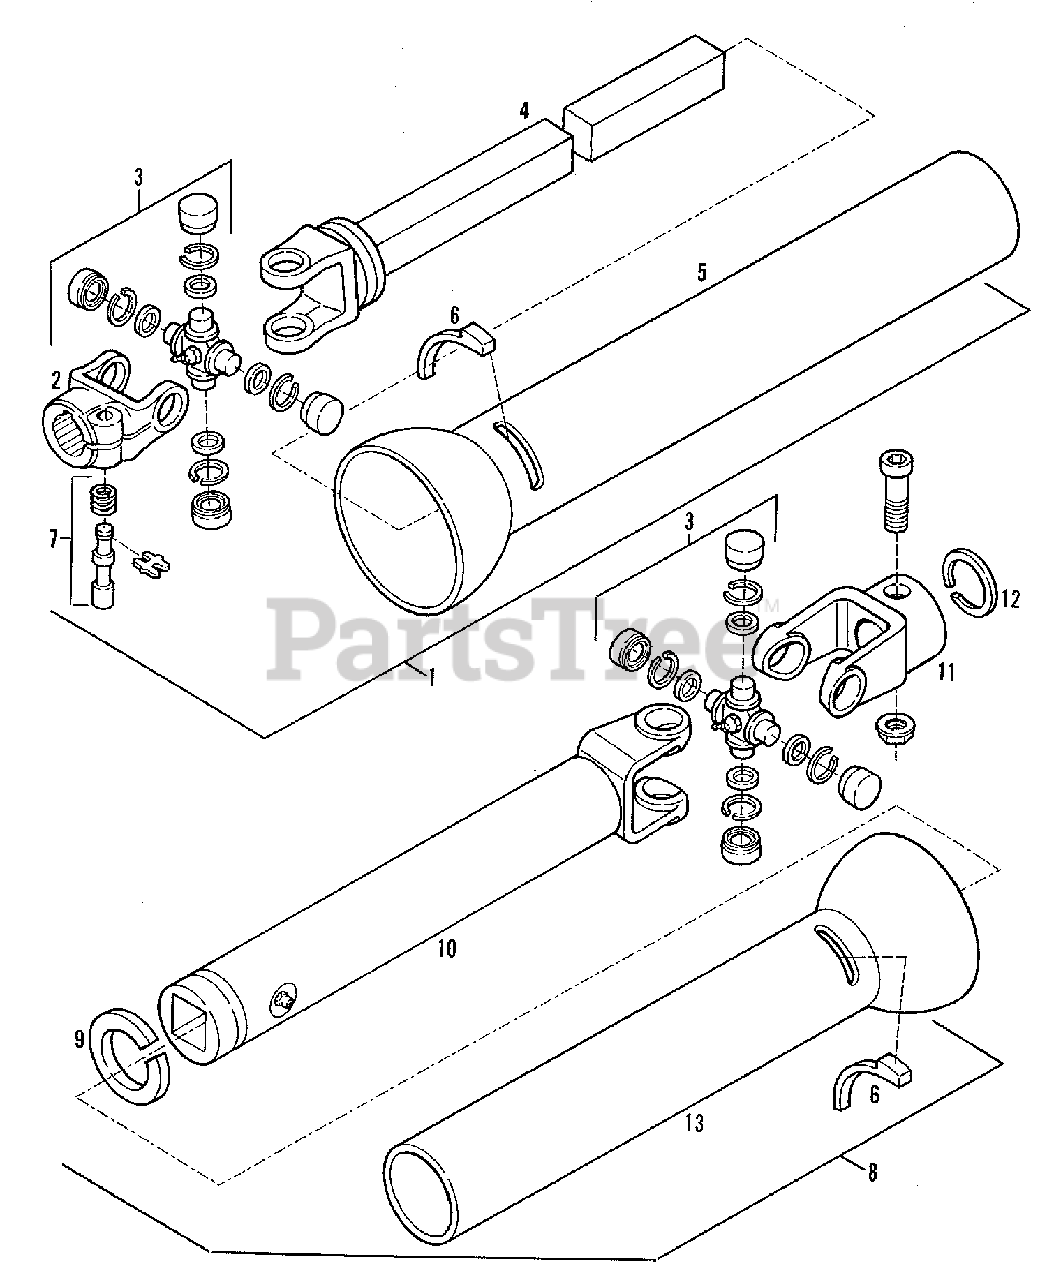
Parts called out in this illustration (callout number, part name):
1	PTO ASSEMBLY, Tractor End
2	YOKE, Tractor End
3	U-JOINT KIT
4	SHAFT & YOKE ASSEMBLY
5	SHIELD, Outer
6	BEARING, Shield
7	SPRING, Lock, Pin & x-Washer
8	PTO ASSEMBLY, Implement End
9	BEARING, Nylon
10	TUBE & YOKE ASSEMBLY
11	YOKE, Gearbox
11	CAPSCREW, Hex Socket Head, 3/8NC x 2
11	NUT, Lock, Flange, 3/8NC
12	RING, Retaining
13	SHIELD, Inner
